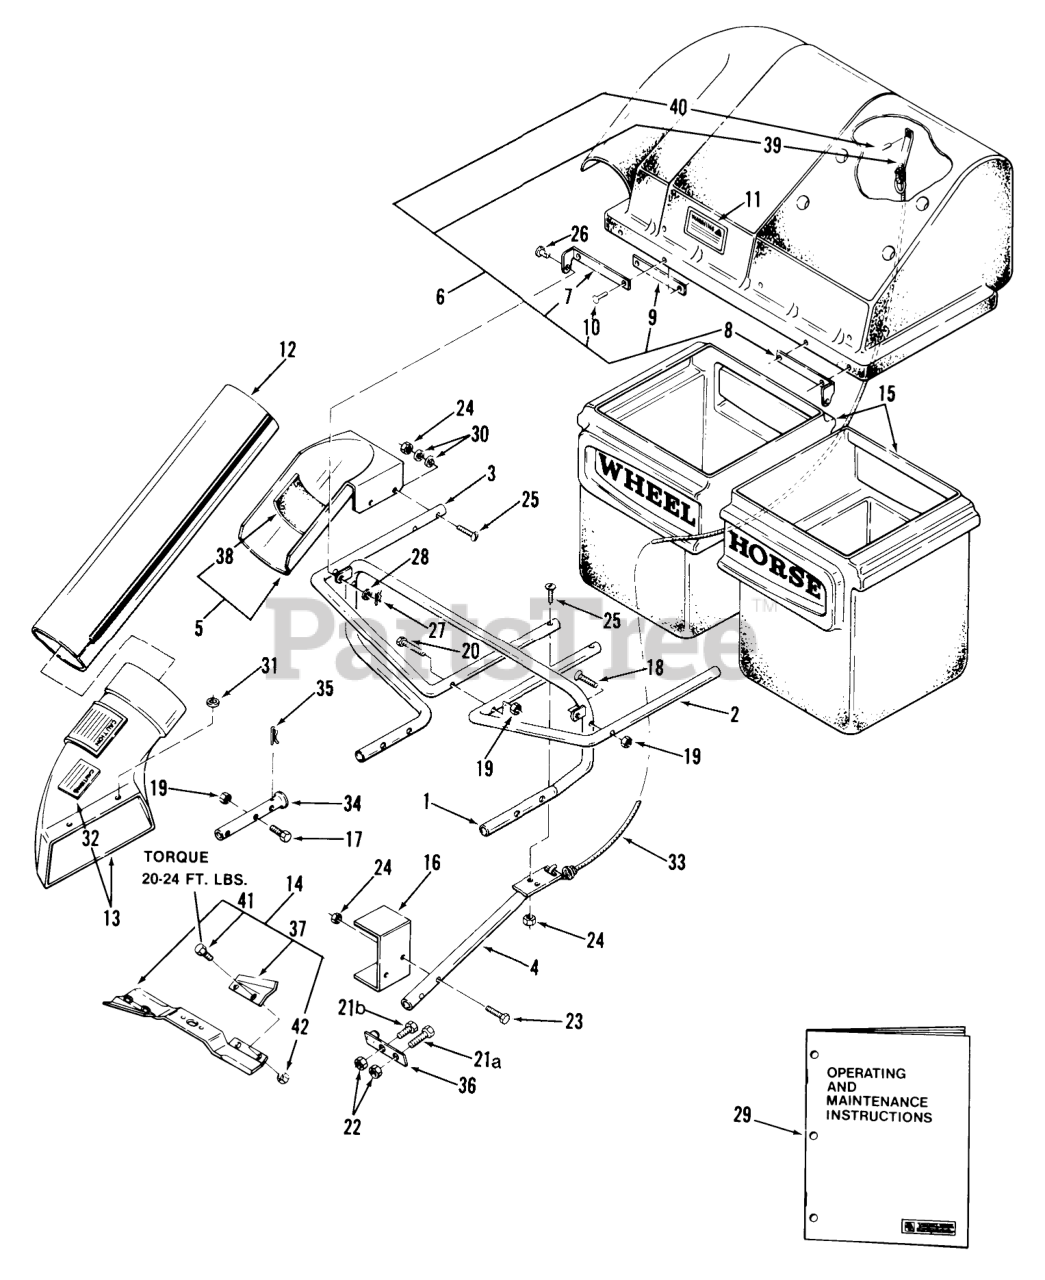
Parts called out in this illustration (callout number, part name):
1	Main Frame
2	SUPPORT-LEFT TUBE
3	Support Tube R. H.
4	ASSY-BRACE TUBE
5	Collector Tube Suport
6	Collector Top Assy.
7	Hinge R.H.
8	Hinge L.H.
9	BACKING PLATE
10	Poprivet 5/32 x 1/2 Long
11	DECAL-WARNING
12	Tube
13	ASSY-ELBOW
14	High Lift Blade
15	CAN-CLIPPINGS
16	Muffler Shield (8 HP Engine Only)
17	HHCS
18	Screw Flat Hd. Mach. 5/16 x 2 1/2
19	Nut
20	HHCS
22	Nut
23	Bolt 1/4-20 X 1 1/2
24	Nut
25	Srew Flat Hd. Mach. 1/4-20 x 1 1/4
26	PIN
27	Hairpin Cotter
28	Washer
29	Operating and Maintenance Instructions
30	WASHER
31	Collar
32	DECAL-CAUTION
33	Strap
34	Quick-Attach Tube
35	Pin-Cotter
36	Pin Mounting
37	Lift Tab Kit
39	Bracket
40	POPRIVET
41	BOLT 5/16-18X5/8
42	NUT-LOCK 5/16-18
